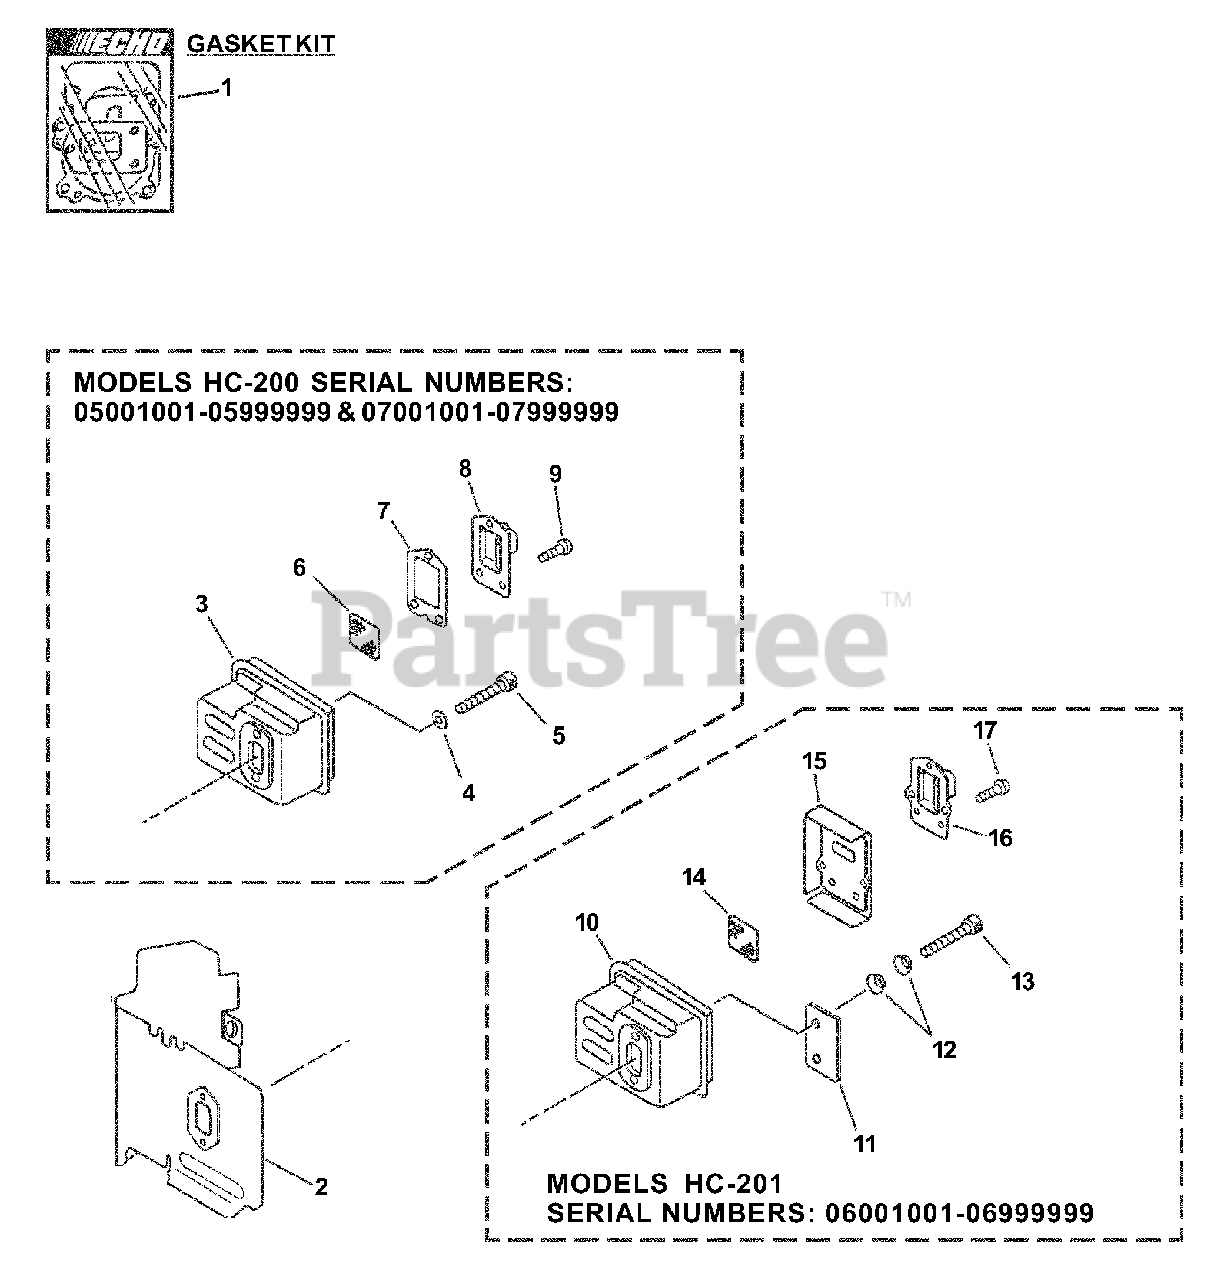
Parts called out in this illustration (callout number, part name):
1	GASKET KIT
2	SHIELD, EXHAUST
4	WASHER - 5
5	SCREW - 5X55
6	SCREEN, SPARK ARRESTOR
7	GASKET, EXHAUST
8	GUIDE, EXHAUST
9	SCREW - 4X10
10	MUFFLER
12	WASHER - CONICAL
13	SCREW - 5X55
14	SCREEN, SPARK ARRESTOR
15	GASKET, EXHAUST
16	GUIDE, EXHAUST
17	SCREW - 4X10
